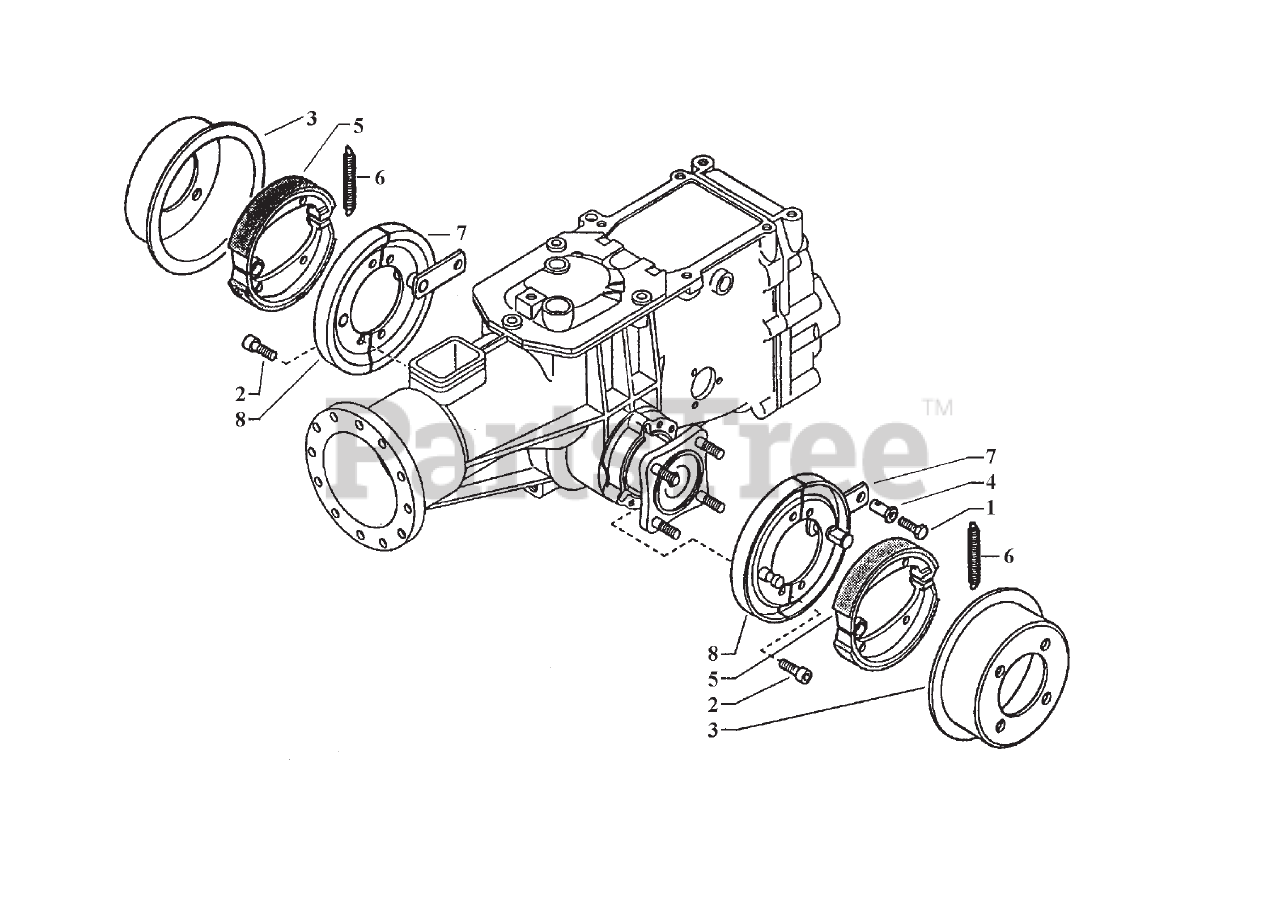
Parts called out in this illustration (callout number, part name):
1	CAP SCREW, M6X14
2	CAP SCREW, M8X25
3	BRAKE DRUM
4	PIN, CABLE CLAMP
5	BRAKE SHOE
6	SPRING
7	LEVER
8	PIN, HALF DISC
